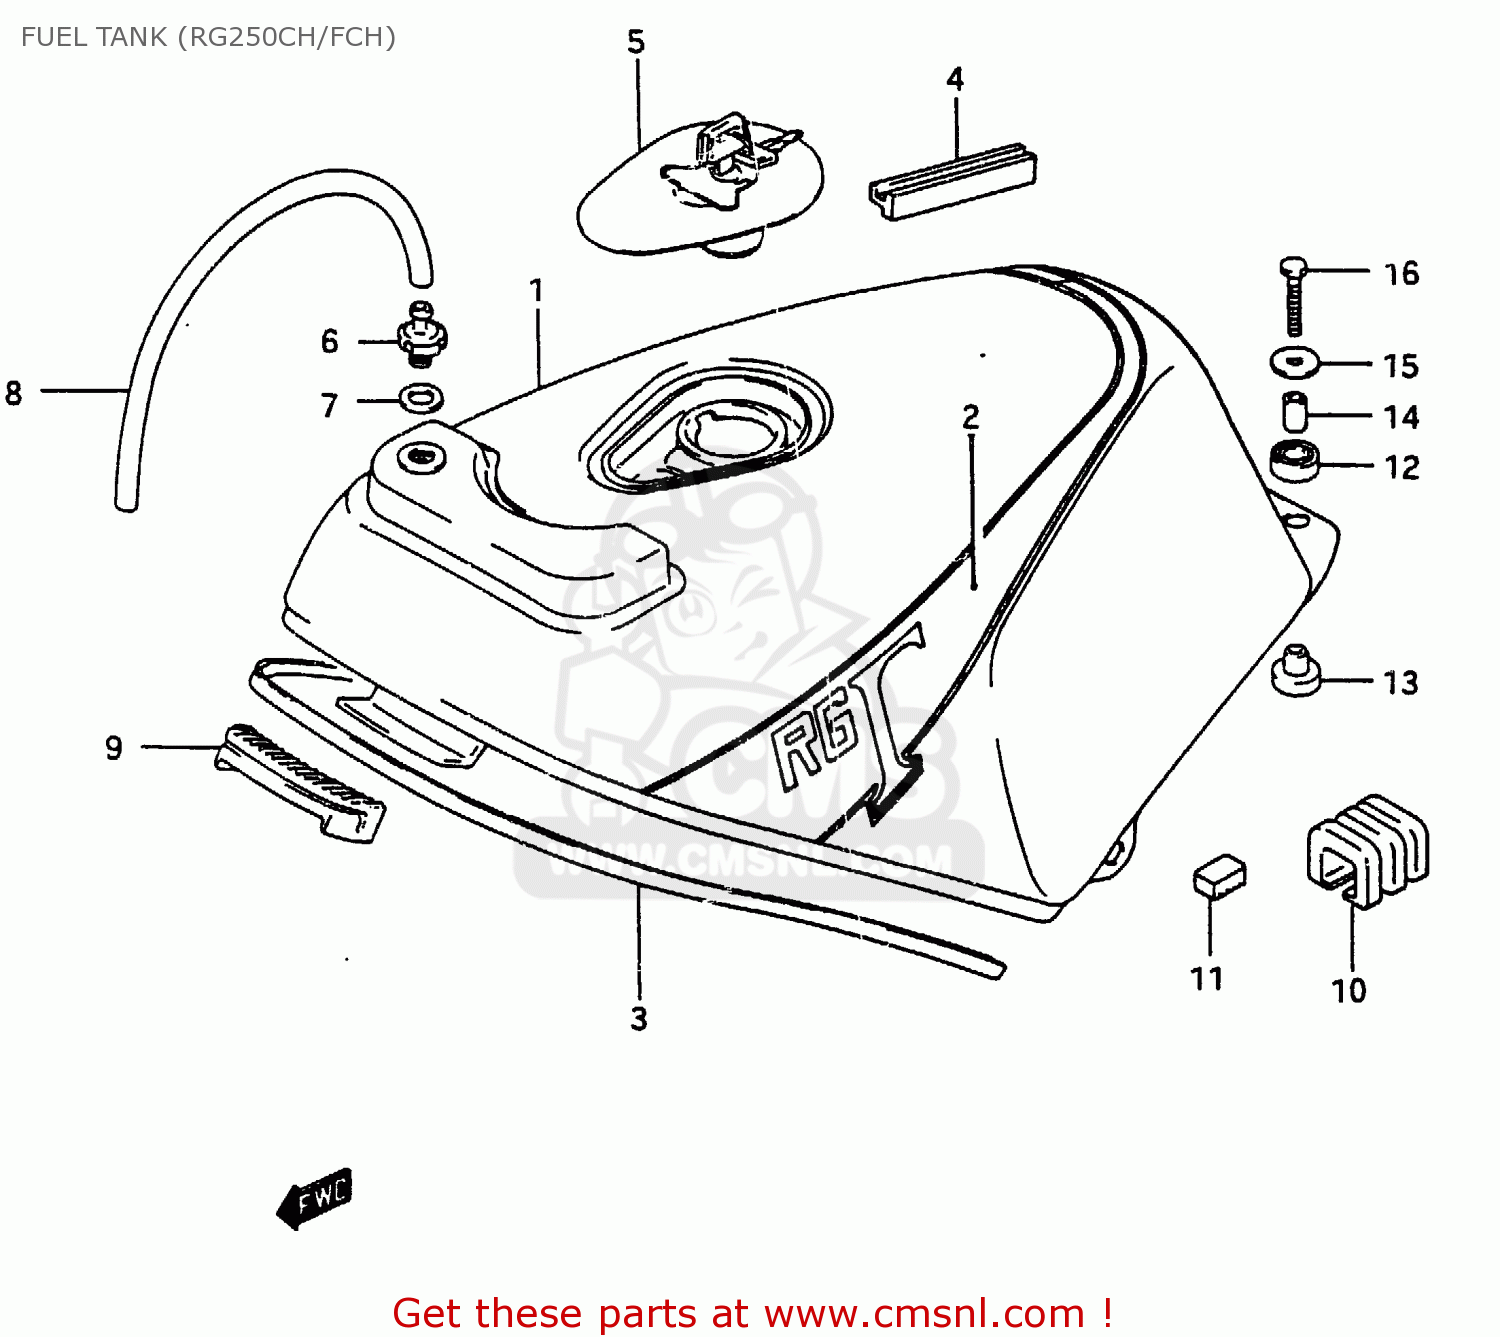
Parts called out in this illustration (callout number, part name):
1	TANK SET, FUEL
2	TAPE SET, FUEL TANK
3	MOLDING, FUEL TANK
4	MOLDING,FUEL TANK
5	CAP ASSY, FUEL TANK
6	PLUG, FUEL TANK BREATHER
7	GASKET(12.5X20X2.5) (NAS)
8	HOSE
9	CUSHION,FUEL TANK FR
10	CUSHION, FUEL TANK CENTER
11	CUSHION,FUEL TANK SIDE
12	CUSHION
13	CUSHION
14	SPACER
15	WASHER (6.5X24X1.6)
16	BOLT ,6X35
